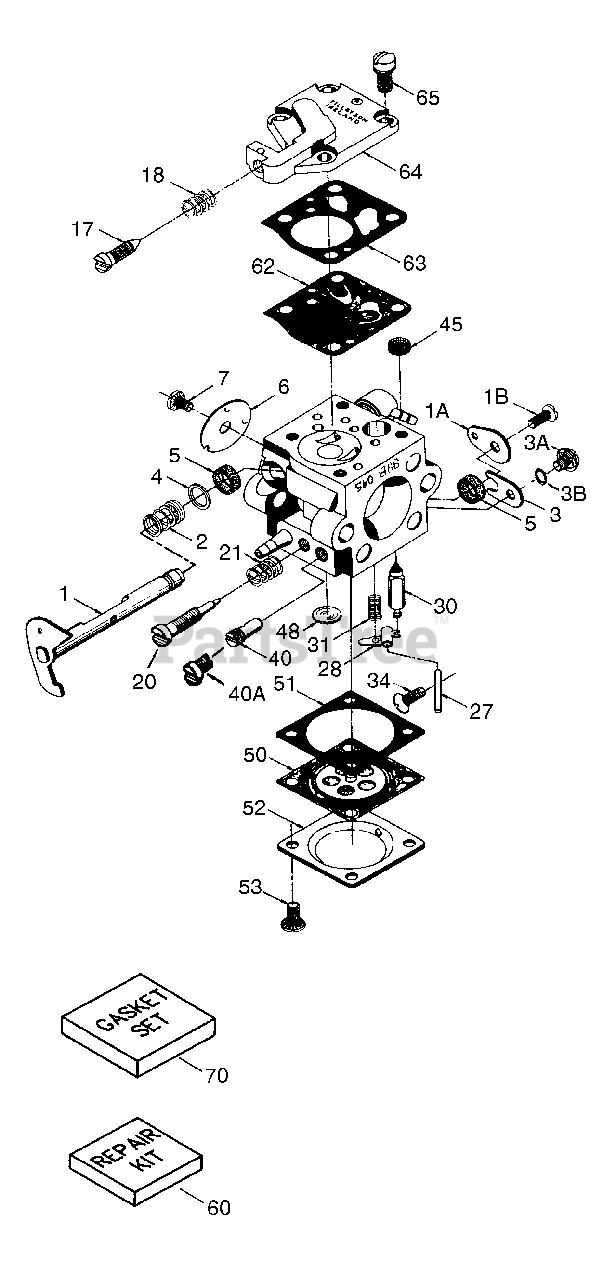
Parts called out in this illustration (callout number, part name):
1	Throttle Shaft & Lever Ass'y.
2	Throttle Return Spring
3	Dust Seal Retainer
3A	Dust Seal Retainer Screw
4	Dust Seal Washer
5	Dust Seal
6	Throttle Shutter
7	Throttle Shutter Screw
17	Idle Speed Screw
20	Idle Mixture Screw
21	Idle Tension Spring
27	Hinge Pin
28	* Metering Lever
30	* Inlet Needle
31	Metering Lever Spring
34	Metering Lever Pin Screw
40	High Speed Jet
40A	High Speed Jet Cap
45	* Fuel Inlet Screen
48	* Welch Plug
50	* Diaphragm (Included in 60 & 70)
51	* Cover Gasket (Included in 60 & 70)
53	Cover Screw
60	Repair Kit (Incl. items marked PK in notes) Incl. (1) each of part #'s6329 02, 632903, 632904, 632907,632908, 63 2915, 632918, 632919
62	* Pump Diaphragm (Included in 60 & 70)
63	* Pump Gasket (Included in 60 & 70)
64	Pump Cover
65	Pump Cover Screw
70	Diaghragm/Gasket Set Incl. 50, 51, 62 & 63
